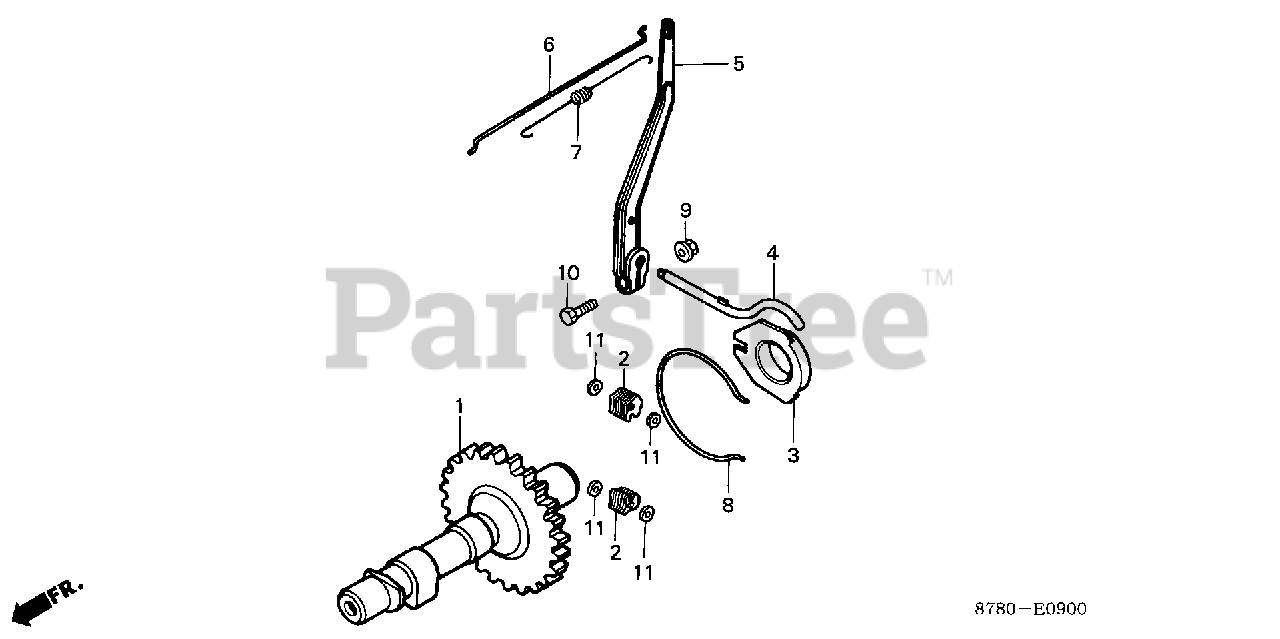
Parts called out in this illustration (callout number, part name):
2	WEIGHT, GOVERNOR (NOT AVAILABLE)
3	SLIDER, GOVERNOR
4	SHAFT, GOVERNOR ARM
5	ARM, GOVERNOR
6	ROD, GOVERNOR (NOT AVAILABLE)
7	SPRING, THROTTLE RETURN (NOT AVAILABLE)
8	CENTER, GOVERNOR WEIGHT
9	NUT, FLANGE (6MM)
10	BOLT, HEX. (6X20)
11	WASHER, PLAIN (3MM)
